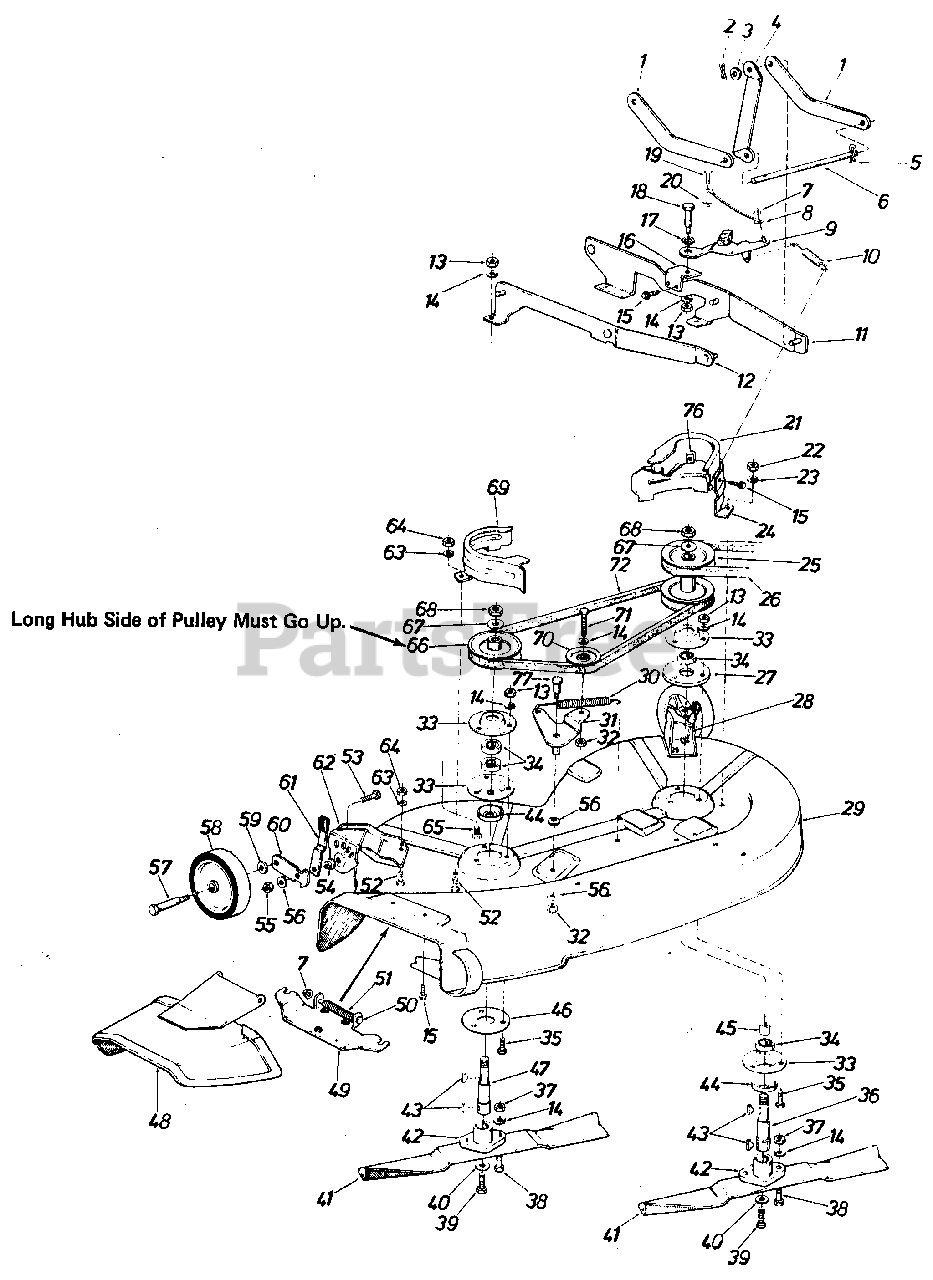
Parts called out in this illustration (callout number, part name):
3	Fl-Wash. 50" I.D. x 1.00" O.D. x .090 Thk.
6	Deck Connecting Rod
7	Push Cap 1/4" Rod
8	Brake Cable Ass'y.
9	Spindle Brake Arm Ass'y.
10	Extension Spring
11	Hanger Brk't. Ass'y. L.H. Side
12	Hanger Brk't. Ass'y. R.H. Side
13	Hex Nut 5/16-18 Thd.*
14	L-Wash. 5/16" I.D.*
15	Hex Wash. Hd. Self-Tap Scr. 1/4-20 x .50" Lg.
16	Spindle Brake Pivot Brk't.
17	Wave Wash. .438" I.D. x .750" O.D. x .15 Thk.
18	Shld. Bolt .437" Dia. x .162" Lg. 5/16-18 Thd.
19	Clevis Pin 1/4" Dia. x 1.00" Lg.
20	Hairpin Cotter 1/4" Dia.
21	Upper Belt Guard L.H. Side
22	Hex Nut 1/4-20 Thd.*
23	L-Wash. 1/4" I.D.*
24	Lower Belt Guard L.H. Side
25	Deck Drive Pulley
26	"V"-Belt 1/2" x 51.0" Lg. (Kevlar) "A" Sec.
27	Spindle Spacer Plate
28	Wheel Brk't. L.H. Side
29	38" Deck Ass'y.
30	Extension Spring
31	Deck Idler Brk't. Ass'y.
32	Hex Cent. L-Nut 3/8-16 Thd.
33	Bearing Housing
34	Ball Brg. .787 I.D. x 1.85 O.D x .55
35	Hex Bolt 5/16-18 x 1.0" Lg.*
36	Blade Spindle
37	Hex Nut 5/16-24 Thd.*
38	Hex Bolt 5/16-24 x 1.00" Lg.*
39	Hex Bolt 3/8-24 x 1.50" Lg.*
40	L-Wash. 3/8" I.D. Heavy Duty
41	19" Blade
42	Blade Adpater Kit
43	#6 Hi-Pro Key 5/32 x 5/8" Dia.
44	Bearing Shield
45	Spacer .790" I.D. x 1.0" O.D. x .315 Lg.
46	Deck Reinforcement Plate
47	Blade Spindle
48	Chute Cover Ass'y.
49	Adapter Plate
50	Hinge Pin
51	Torsion Spring
52	Hex Bolt 1/4-20 x .50" Lg.*
53	Hex Bolt 3/8-16 x 1.25" Lg.*
54	Shoulder Spacer
55	Hex Jam L-Nut 3/8-16 Thd.
56	Belleville Wash. .400" I.D. x 1.13" O.D. x .030
57	Shld. Bolt. 498 Dia. x 1.53" Lg.
58	Deck Wheel 5" Plastic Comp.
59	Belleville Wash. .400" I.D. x .88" O.D. x .060
60	Wheel Pivot Bar Deck
61	Spring Lever Ass'y. w/Knob
62	Wheel Brk't. R.H.
63	L-Wash. 1/4" I.D.*
64	Hex Nut 1/4-20 Thd.*
65	Sems Truss Hd. Scr. 5/16-18 x .50" Lg.
65	Sems Truss Hd. Scr. 5/16-18 x .50" Lg.*
66	Pulley 4.75" O.D.
67	L-Wash. 5/8" I.D.*
68	Hex Jam Nut 5/8-18 Thd.
69	Belt Guard
70	4" "V"-Idler Pulley
71	Hex Bolt 3/8-16 x 1.25" Lg.*
72	"V"-Belt .50" x 53.0 Lg. (4L)
76	Speed Nut 1/4-20 Thd.
77	Shld. Bolt .50" Dia. x .71" Lg. 3/8-16 Thd.
